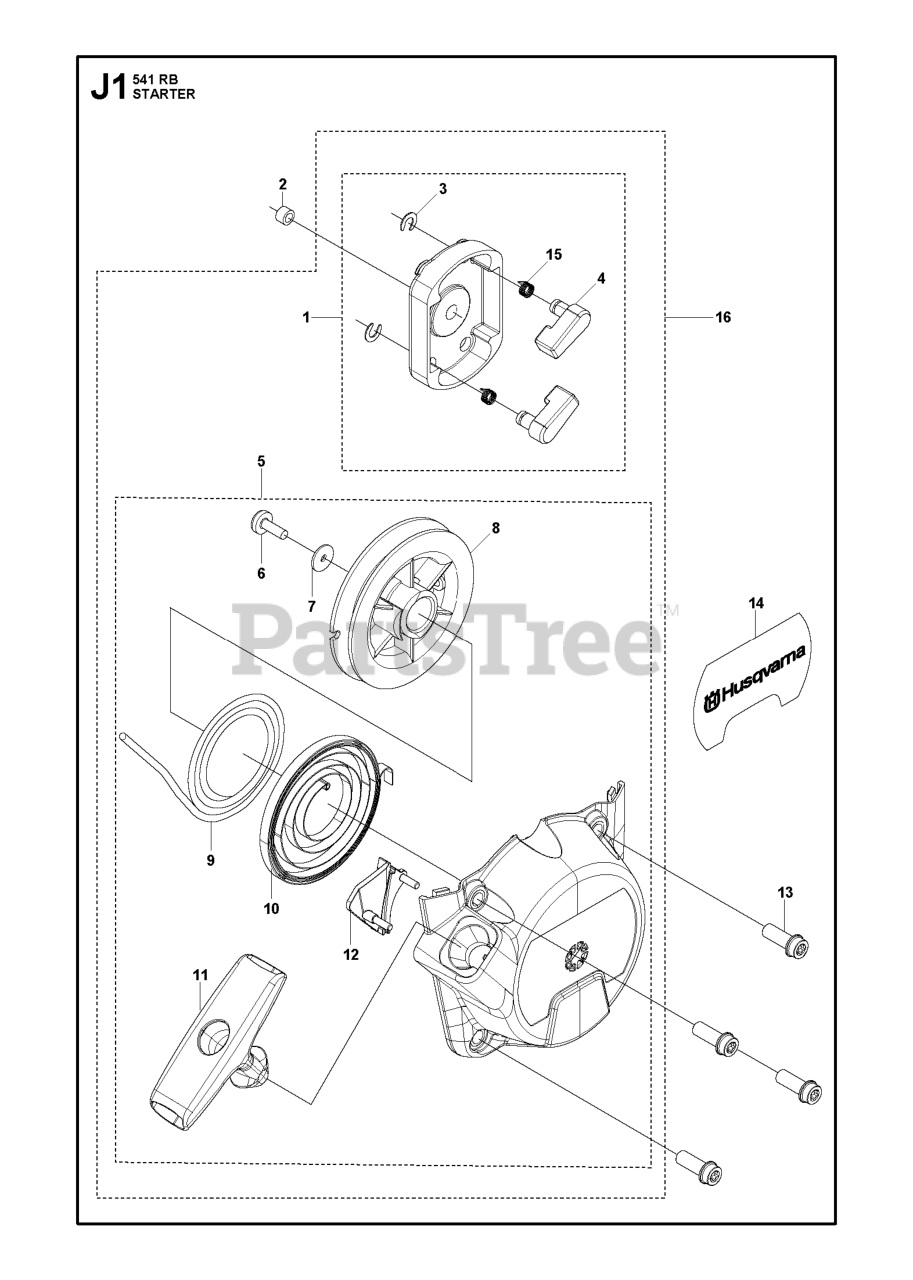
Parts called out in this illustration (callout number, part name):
2	COLLAR
3	CLIP
7	WASHER
10	SPRING
11	HANDLE
15	SPRING
